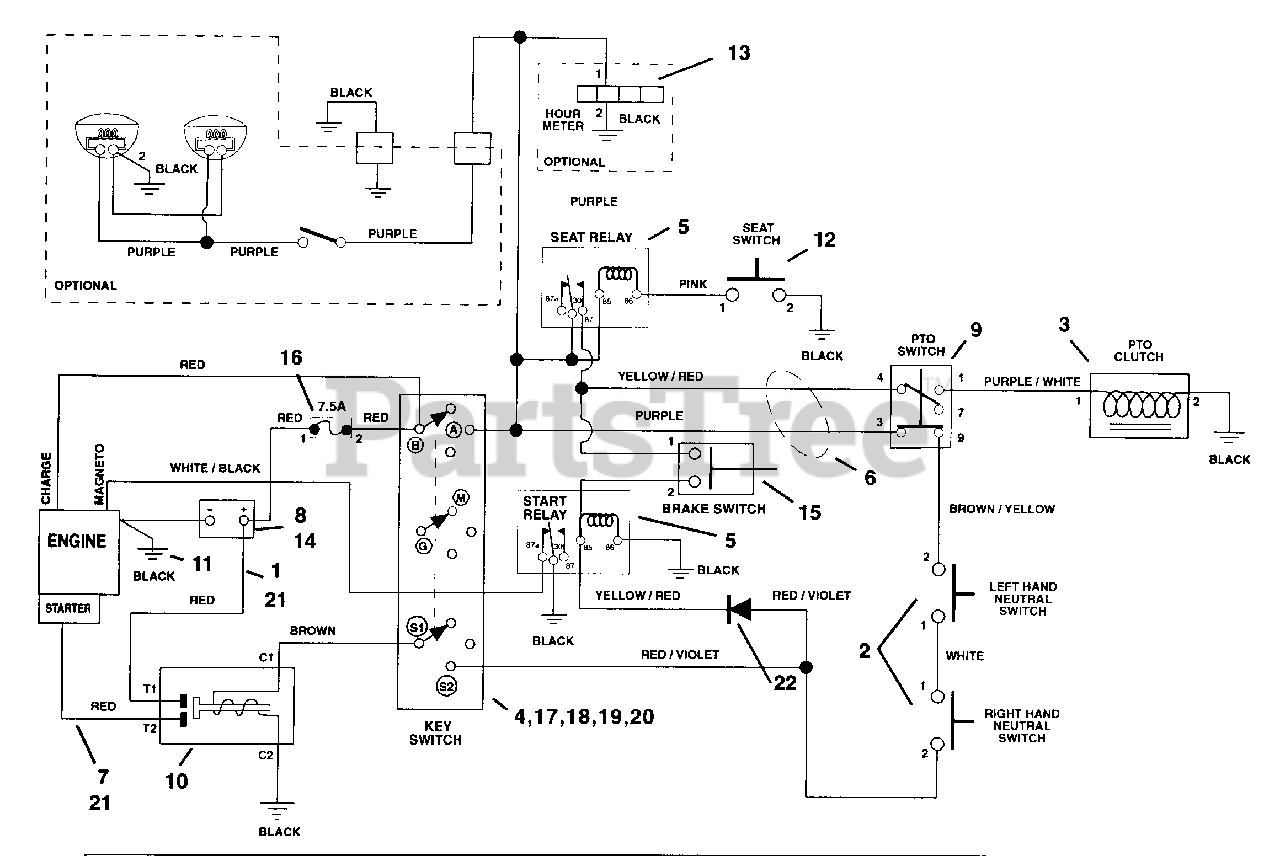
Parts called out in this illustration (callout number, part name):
1	CBL,BATTERY TO SOLENOID
2	SWITCH, NEUTRAL START N.O.
3	CLUTCH, ELECTRIC - WARNER
4	KEY SWITCH
5	RELAY
6	HARNESS, WIRE - 1540
7	START CABLE 22"
8	BATTERY W/ TUBE
9	SWITCH, CLUTCH
10	SOLENOID
11	GROUND CABLE .31X22.00X.31
12	SWITCH- SEAT
13	HOUR METER
14	RUBBER PAD
15	SWITCH- SINGLE POLE N.O.
16	30 AMP Fuse
17	KEY -W/CAP
18	CAP - IGNITION SWITCH
19	NUT- PANEL .562-24 GRECO
20	WSHR-LK-INT .563X.040 PL
21	BOOT, INSULATOR
22	MOLDED DIODE PLUG 1 AMP
